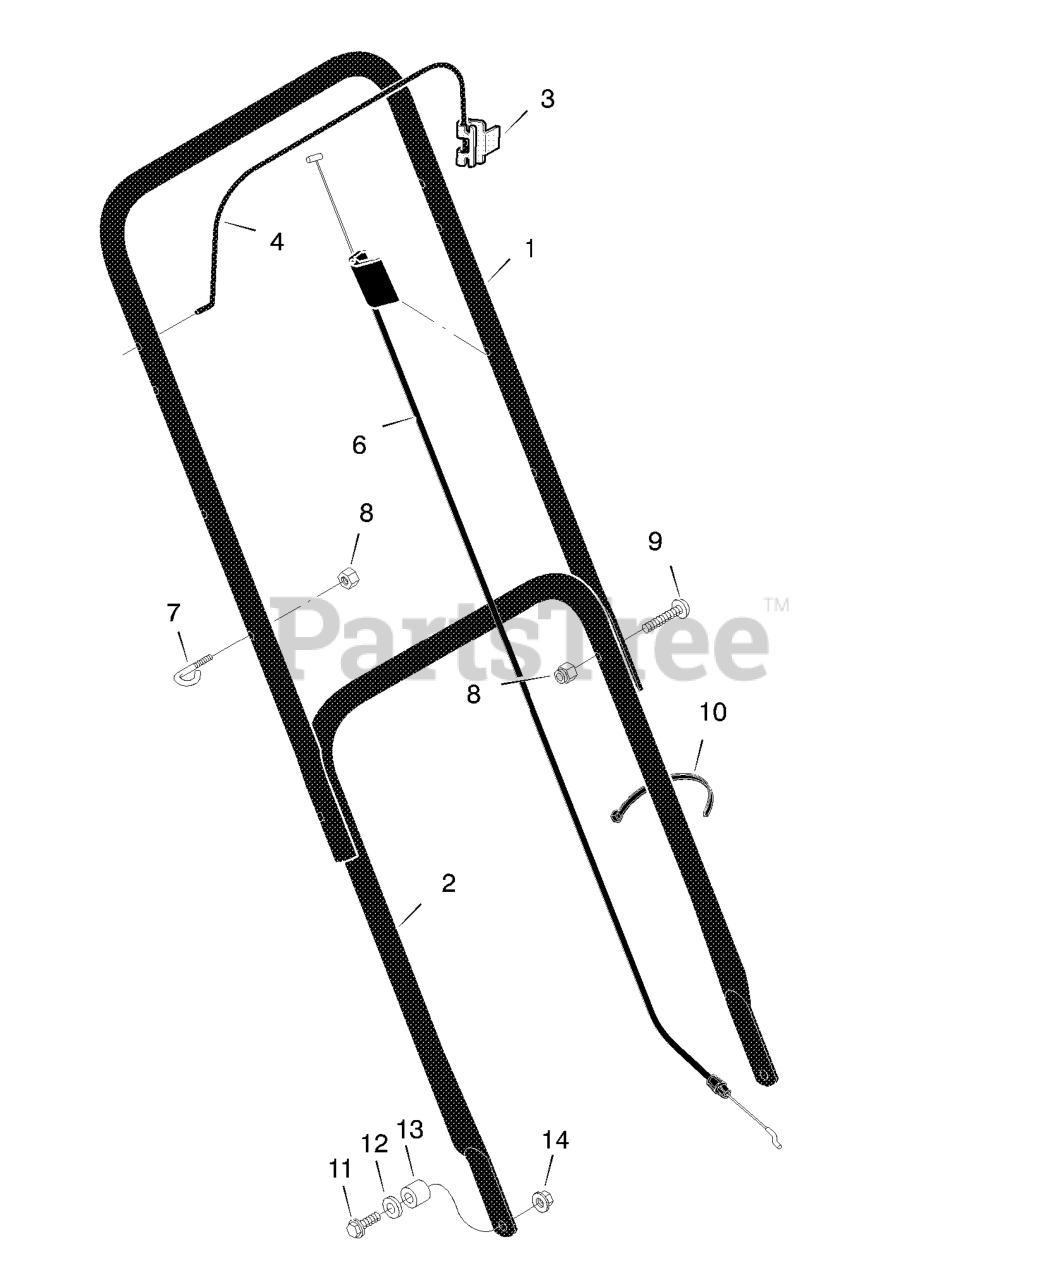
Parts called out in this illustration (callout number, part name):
1	Handle, Upper (Black)
2	Handle, Lower (Black)
3	Bracket, Stop Lever
4	Lever, Stop
6	Engine Stop Cable
7	GUIDE, ROPE
8	Locknut
10	Fastener, Cable
11	Bolt
12	Washer
14	Nut
